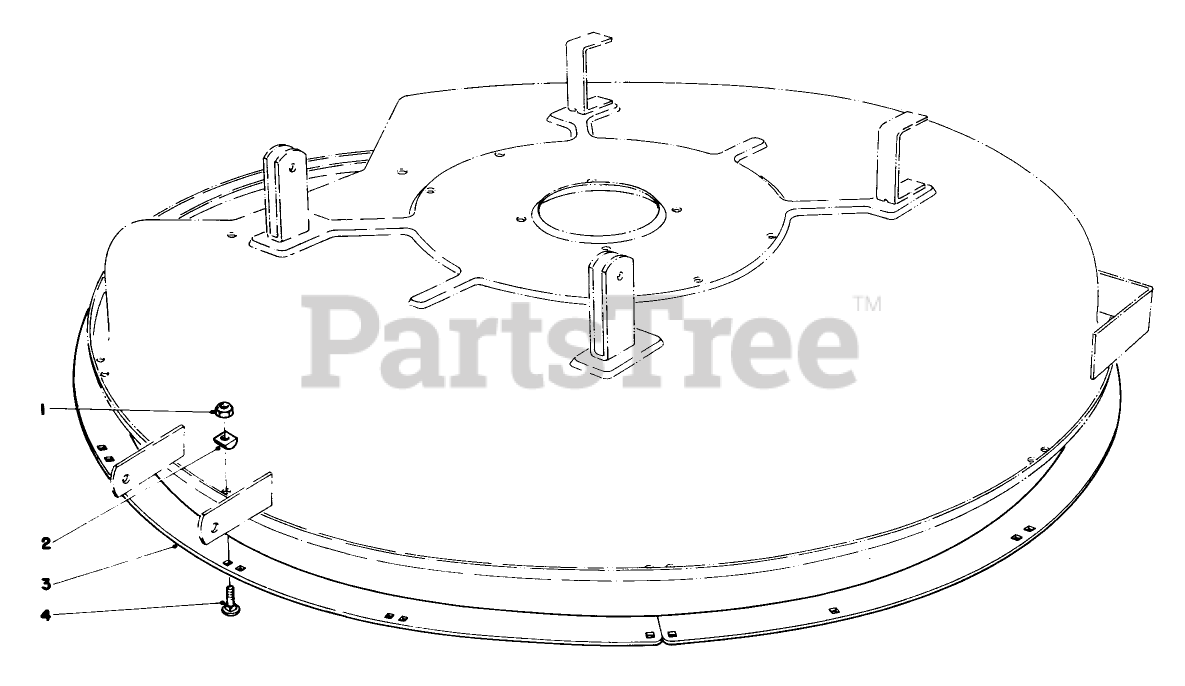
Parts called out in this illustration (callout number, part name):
1	NUT-LOCK, NI
3	DECK RING *B
4	BOLT-CARR
